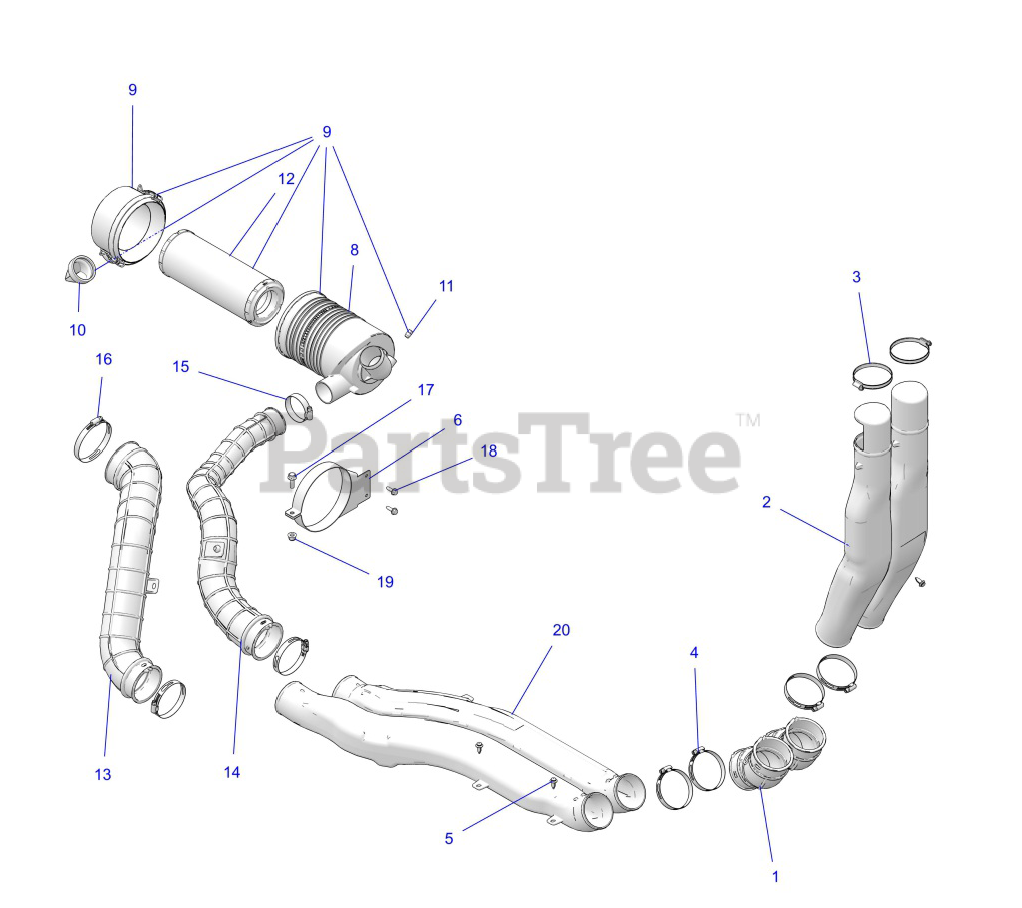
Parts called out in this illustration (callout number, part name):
1	HOSE-JOINT
2	DUCT-INTAKE,FRONT
3	CLAMP-BAND,NARROW 70-90MM
4	CLAMP-HOSE SLOTTED,75-90 DIA
5	RIVET-TUFLOK,.315-.325X.787 (5
6	WELD-MOUNT,AIRBOX
7	ASM-AIR INTAKE,ULTRAWEB
8	ASM., AIRBOX, MAIN
9	ASM-LID,AIRBOX
10	VALVE-AIRBOX
11	PLUG-AIRBOX
13	HOSE-CLUTCH INLET TO TUNNEL
14	HOSE-INTAKE,PRE-FILTER
15	CLAMP, HOSE, S.S.(10)
16	CLAMP-HOSE SLOTTED,89-100 DIA
17	BOLT-M8X1.25X25,HXFLG-OLIVE D
18	SCR-TXTH-M6X1.0X25 RIE
19	NUT-M8X1.25,FLG,NYLOC-OLIVE D
20	DUCT-TUNNEL
